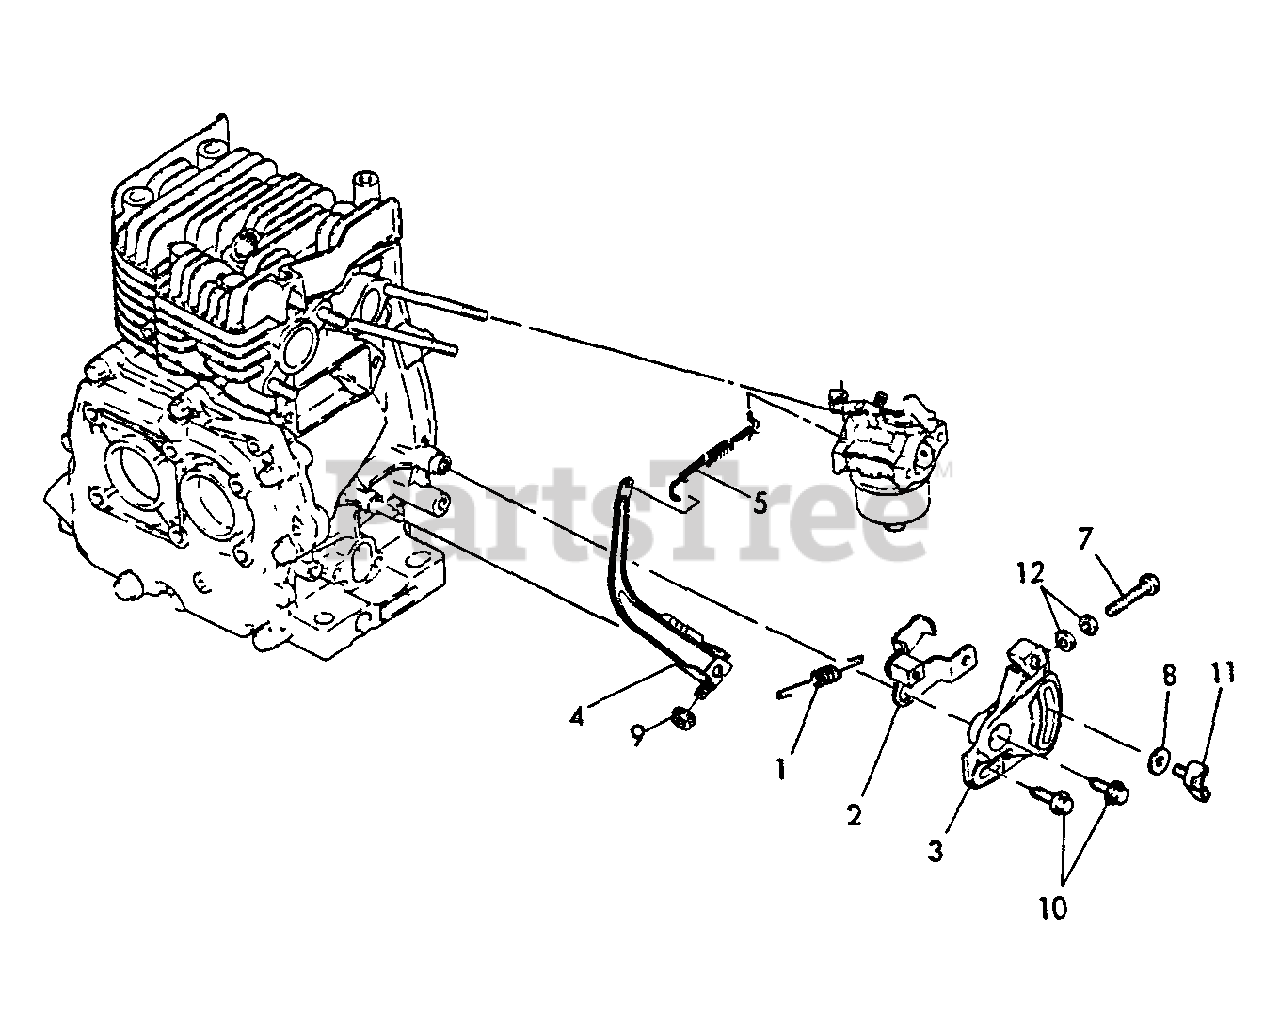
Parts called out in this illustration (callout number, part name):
1	SPRING, REGULATOR
2	REGULATOR HANDLE ASSY
3	BRACKET, REGULATOR
4	LEVER, GOVERNOR
5	LINK, THROTTLE
6	SPRING
7	BOLT
8	WASHER - 6
9	NUT - 6 -- FLANGE
10	BOLT - 6X20
11	THUMBSCREW
12	LOCKNUT - 6 -- PLATED
